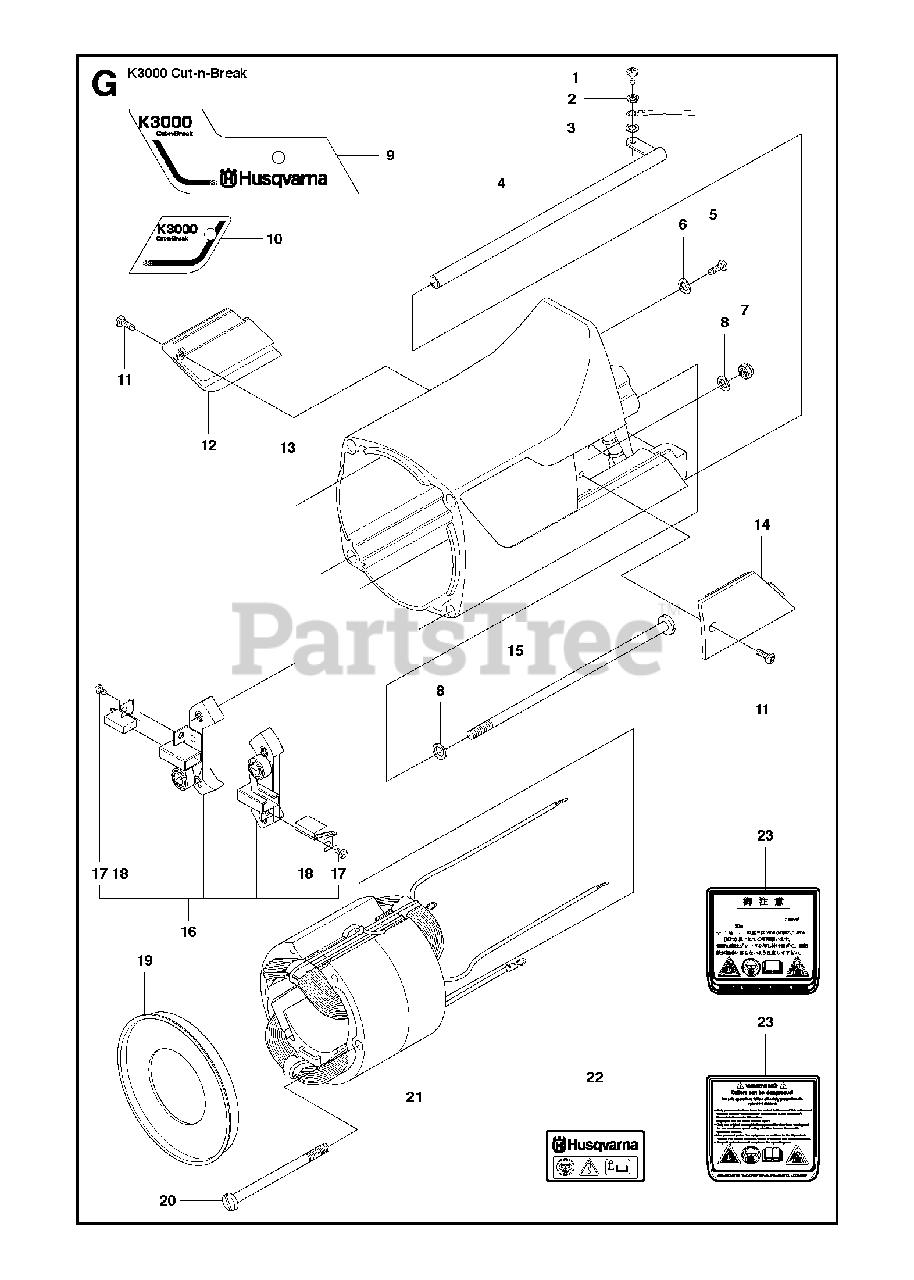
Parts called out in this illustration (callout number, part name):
1	SCREW CRPANM
6	SPRING WASHER
8	SPRING WASHER
11	SCREW CCRPANT
13	MOTOR HOUSING
16	BRUSH HOLDERIncl. 17, 18
17	SCREW SLPANM
18	CARBON BRUSH
19	AIR STREAM DIRECTOR
21	STATOR ASSY100 - 120V
21	STATOR ASSY230V
23	LABELUSA
